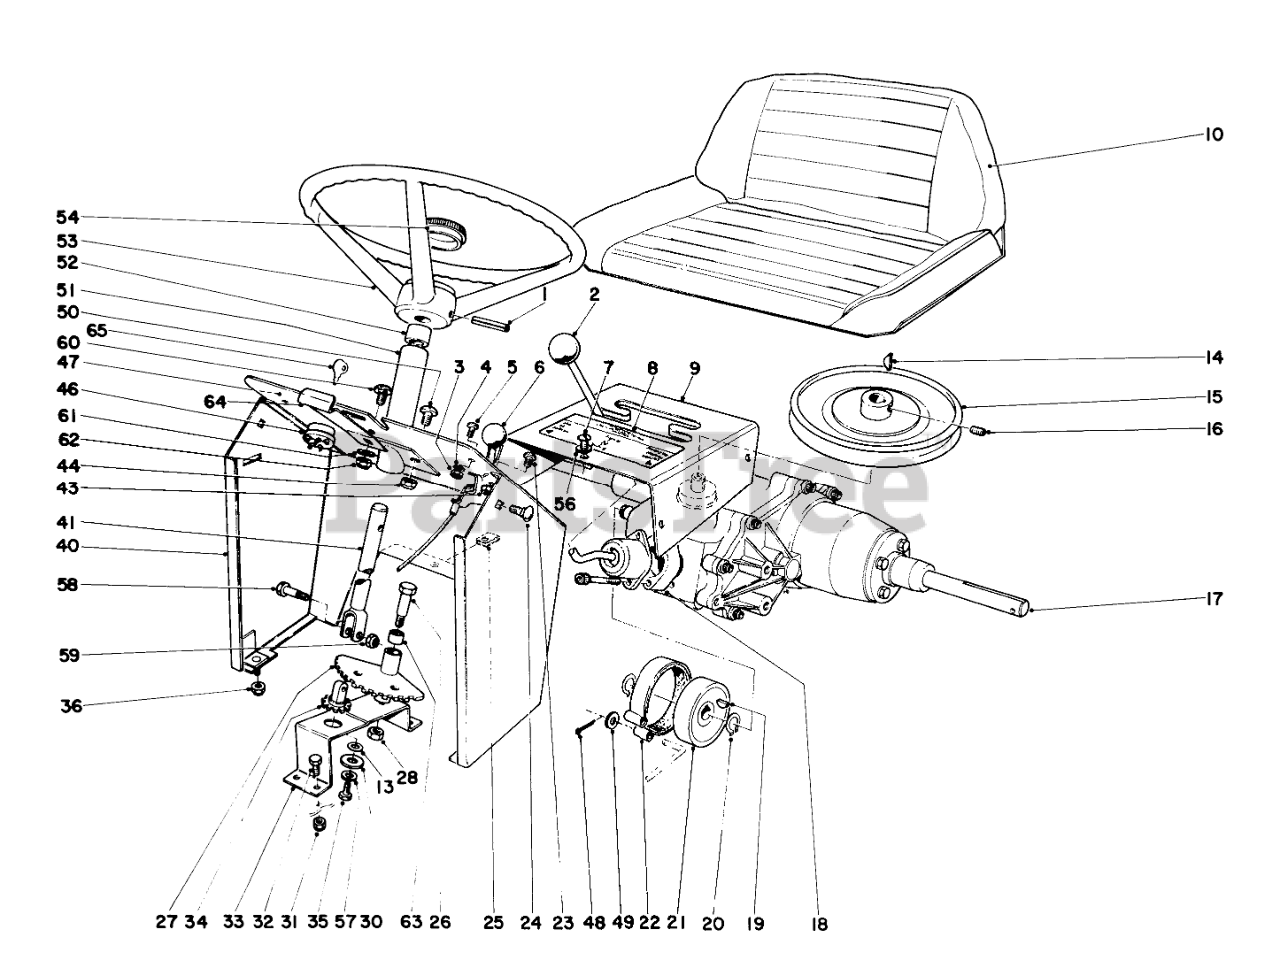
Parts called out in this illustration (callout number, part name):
1	Roll Pin
3	NUT-HEX
4	WASHER-LOCK, EXT
6	Throttle Control
7	SCREW
8	Decal Shift Pattern
9	Tunnel
13	Spacer
14	KEY-WOODRUFF
15	Pulley
16	Set Screw
17	Transaxle
18	Extension Shift Housing
19	KEY-WOODRUFF
20	RING-SNAP, EXTERNAL
21	Brake Drum
22	Brake Band
24	BOLT-CARR
25	SPEED NUT
26	Shoulder Bolt
27	Gear Steering
28	Nut
30	Washer
31	Nut
32	SCREW-HH
33	Bracket
34	Pinion Steering
35	SCREW-HH
36	Nut
41	Steering Shaft
43	NUT-HEX
44	Nut
46	STARTER SWITCH
47	Decal Dash Panel (Recoil)
48	PIN-COTTER
49	WASHER-PLAIN
50	Truss Head Screw
51	Steering Tube (Incl. Ref. #52)
52	Bushing
53	Steering Wheel
54	Steering Wheel Cap
56	WASHER-LOCK
57	WASHER-LOCK
58	Screw Shoulder
59	NUT-HEX
60	Carriage Bolt
61	WASHER-FLAT
62	NUT-LOCK, CONE
63	BUSHING
64	Hood Latch
65	Key
